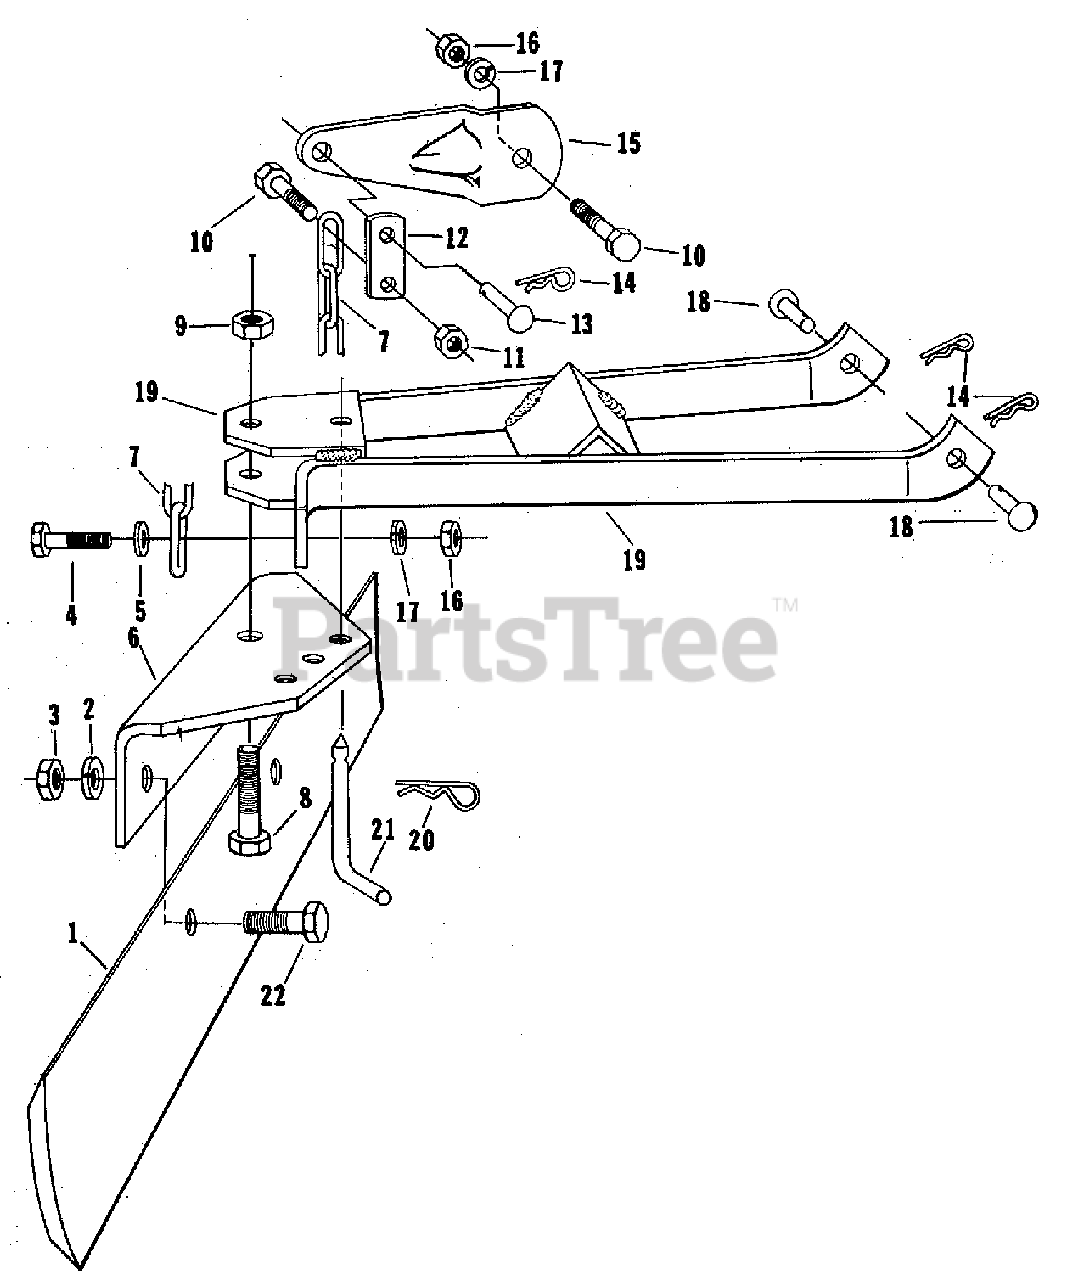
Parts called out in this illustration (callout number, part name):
1	BLADE, Grader, 40"
2	WASHER, Lock, 5/8
3	NUT, Hex, 5/8-11
4	SCREW, Hex Cap, 3/8-16 x 1-1/4
5	WASHER, Flat, 3/8
8	SCREW, Hex Cap, 5/8-11 x 3
9	NUT, Hex, 5/8-11
10	SCREW, Hex Cap, 3/8-16 x 1
11	NUT, Hex, 3/8-16
15	LEVER, Mower Lift
16	NUT, Hex, 3/8-16
17	WASHER, Lock, 3/8
19	BAR ASSEMBLY, Pull
22	SCREW, Cap, 5/8-11 x 2
